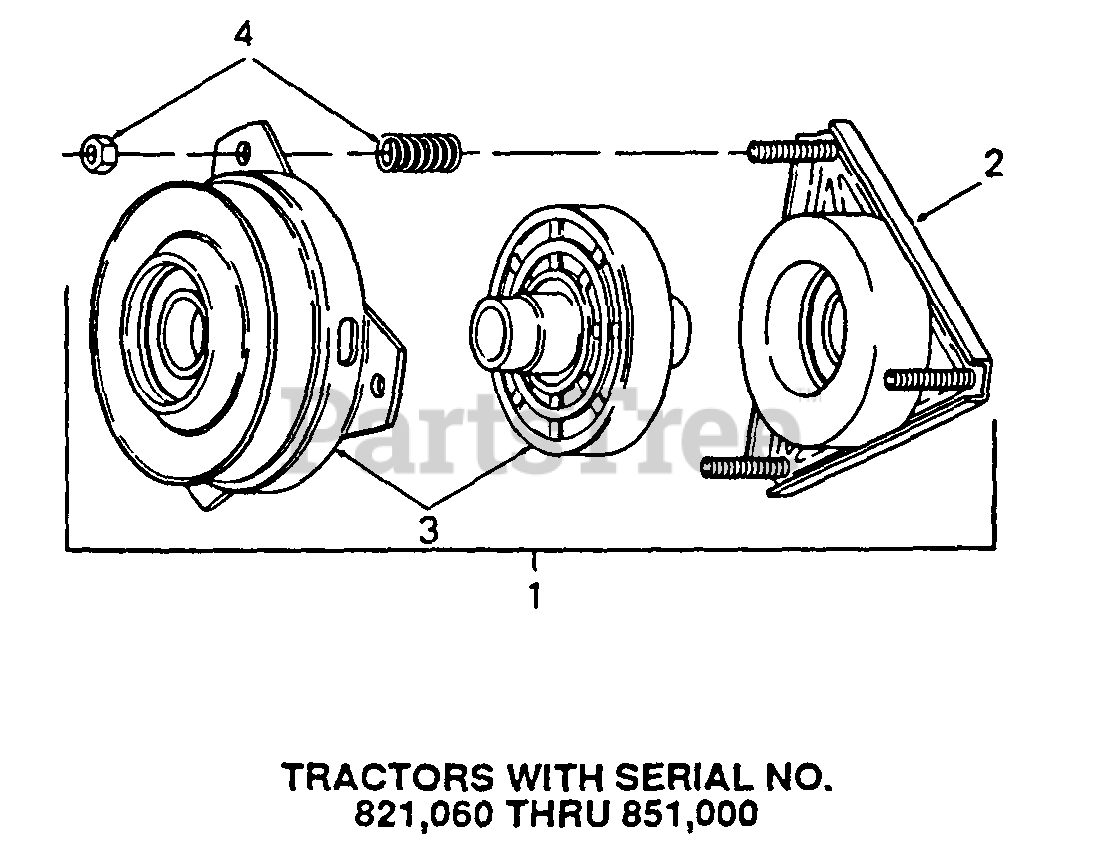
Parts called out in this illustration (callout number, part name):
1	Clutch Assy, PTO
2	Field Assy
3	Kit, Rotor & Armature
4	Mounting Accessories
